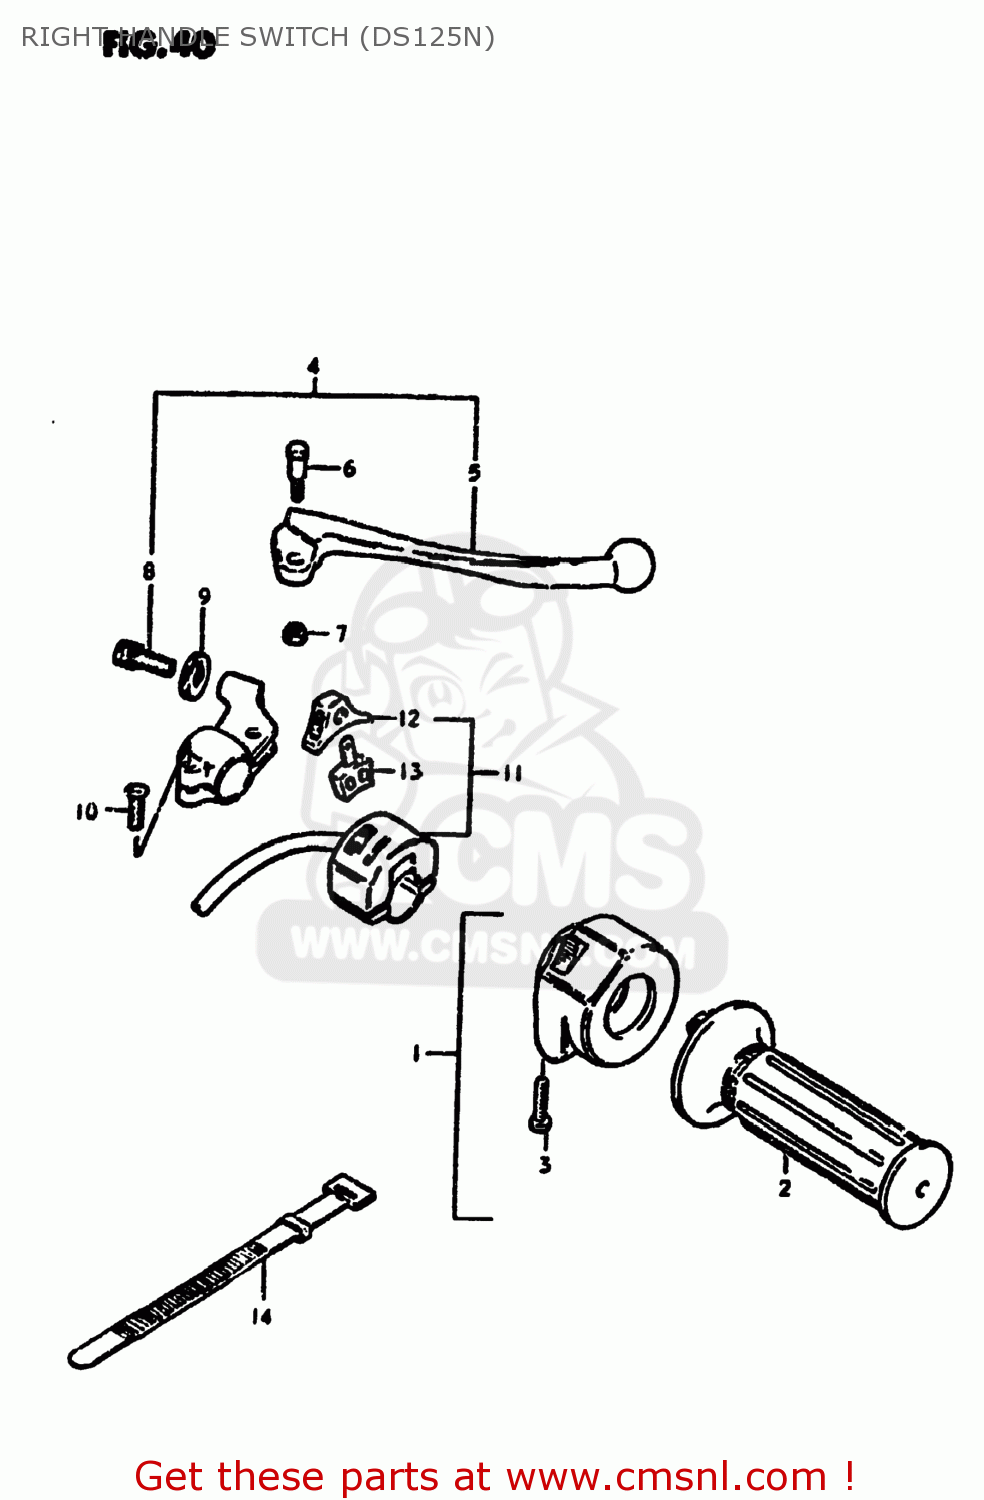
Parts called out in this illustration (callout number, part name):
1	CASE ASSEMBLY,THROTTLE
2	GRIP,THROTTLE
3	SCREW
4	LEVER ASSEMBLY,BRAKE
5	LEVER,BRAKE
6	BOLT,LEVER
7	NUT 6MM
8	ADJUSTER,CABLE
9	NUT,CABLE ADJUSTER
10	SCREW
11	SWITCH ASSEMBLY,LIGHTING
12	KNOB,LIGHTING & DIMMER
13	BLOCK,LIGHTING/DIMMER
14	CLAMP(L:120)
